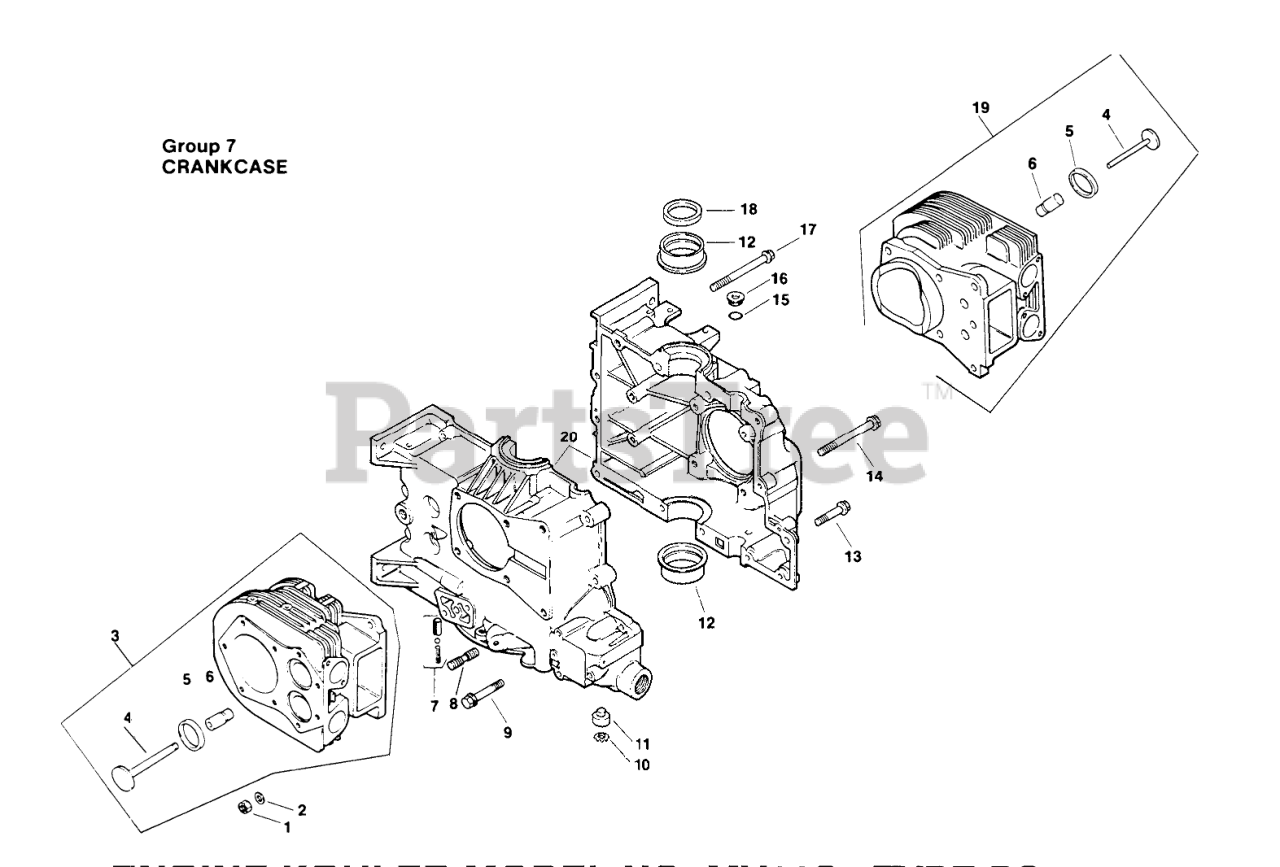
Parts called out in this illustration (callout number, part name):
1	Nut
2	Washer-Flat
3	Kit-#2 Cylinder Barrel (Incl. Ref. #4-6)
4	Valve-Exhaust
5	Inset-Valve Seat
6	Guide-Valve
7	Kit-Oil Relief
8	Stud-Step
9	Screw-Hex. Flange
10	Ring-Retaining
11	Shaft-Governor
12	Bearing-Sleeve (Std.)
13	Screw-Hex. Flange
14	Screw-Hex. Flange
15	O-Ring
16	Plug
17	Screw-Hex Flange
18	SeaI-RearOil
19	Kit-#2 Cylinder Barrel (Incl. Ref. #4-6) Crankcase Service with Short Block 8252230
